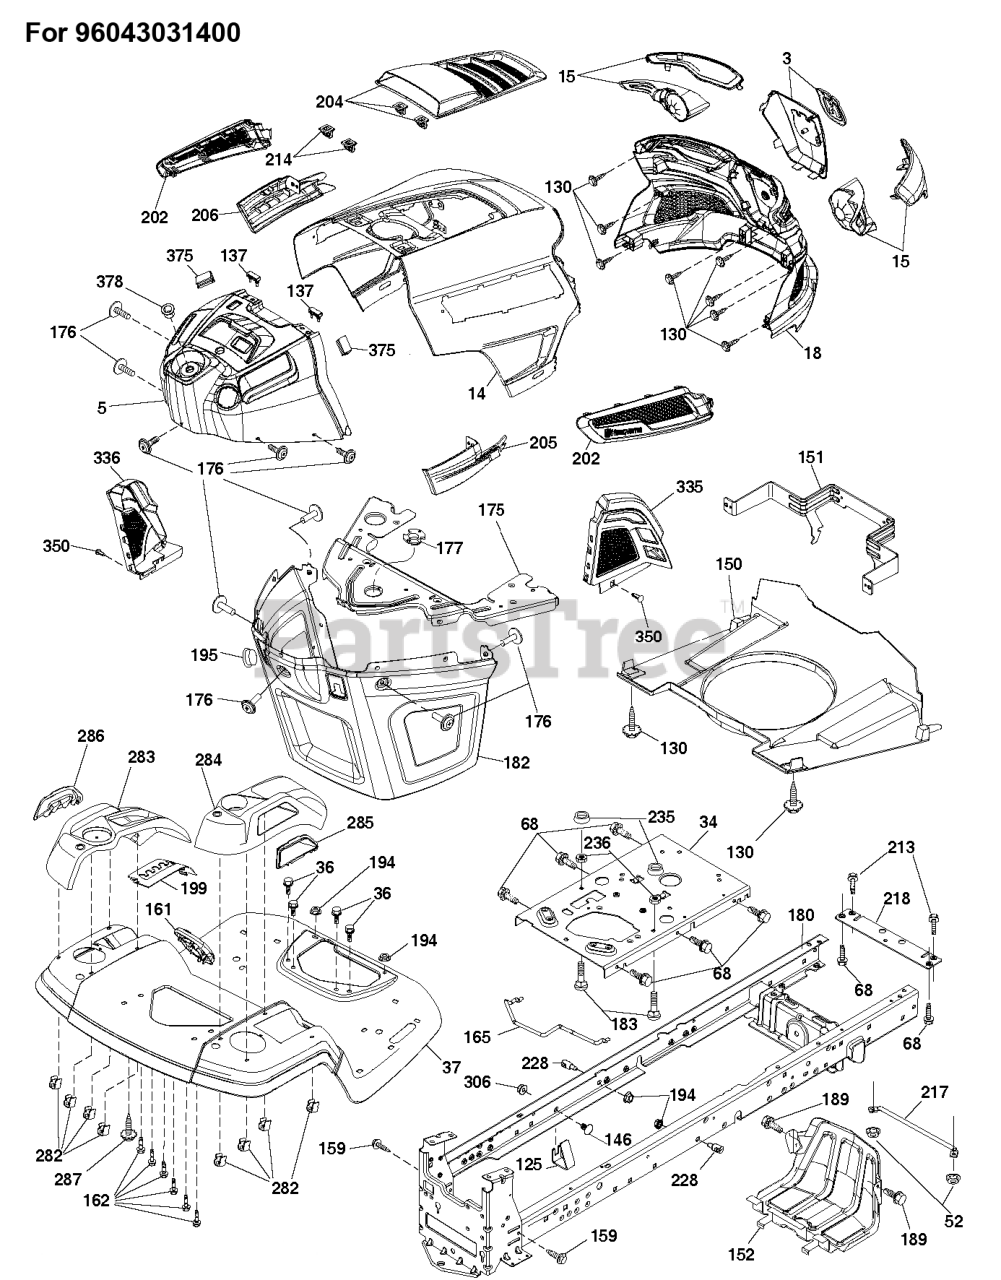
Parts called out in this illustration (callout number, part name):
5	DASH.ASM.W/BUMPERS.READYSTART
14	HOOD.ASM.HUSQVARNA.GT.TEX.ORAN
15	Service Kit
34	PLATE.ENGINE.WELDED.CHASSIS
36	SCREW 5/16"
37	FENDER.TLT.FS.W/CPH/FW/RSF.668
125	CLIP.FUEL.LINE
137	BUMPER DASH
146	BOLT.RDHD.SHT.SQNK.3/8-16X5/8
150	AIR.DUCT.GTV2(2.54"RING HEIGHT
151	BRACKET.PIVOT.HOOD.GT.HUSQ.II
152	SHIELD.BROWNING.PNT.GT.V2
159	SCREW, 3/8-16X3/4
161	WINDOW.FUEL.LT.HUSQ.TEX.498
165	SUPPORT.TANK.REAR.W/TEX
175	PLATE.PNT.CROSSMEMBER.HUSQ/PRE
176	SCREW.#10-24X5/8.RN.QU
177	BUSHING STEERING
180	CHASSIS
182	DASH.LOWER.COMMON.12V.ADAPTOR
189	SCREW
195	PLUG.HOLE.DASH.LOWER.12V.BLK
199	PLATE.DECK.LIFT.HUSQ.LT
202	Vents
205	SIDE.TRIM.RH.GT.HUSQ.II
206	SIDE.TRIM.LH.GT.HUSQ.II.GRAY
213	SCREW HEXAGON HEAD SCREW 5/16-
214	CLIP.RETAINER.TINNER.
217	ROD.PIVOT.HOOD
218	X-PIECE.HOOD.STOP.NON/
228	STUD.FASTNER.W/ANTI-ROTATE
228	STUD.W/"D"ANTI-ROTATION
236	NUT.CENTERLOCK.5/16-
282	CLIP.RETAINER.CONSOLE.LT.HUSQ
283	CONSOLE.DECK.LIFT.R.SDFL.HUSQ
284	CONSOLE.SHFT.PDL.CNTRL.HUSQ.LT
285	CONSOLE INSERT RH
286	CONSOLE.INSRT.LH.HUSQ.LT.BLACK
287	SCREW 1/4X20
306	NUT LOCK FLG 3/8-16 UNC
335	COVER.LOWER.DASH.RH.BLACK
336	COVER-LH.LOWER.DASH.GT2.BLACK
350	CLIP.X-MAS.TREE
375	BUMPER CLIP-ON. DASH 1"
378	BUSHING FLANGE; PLASTIC
